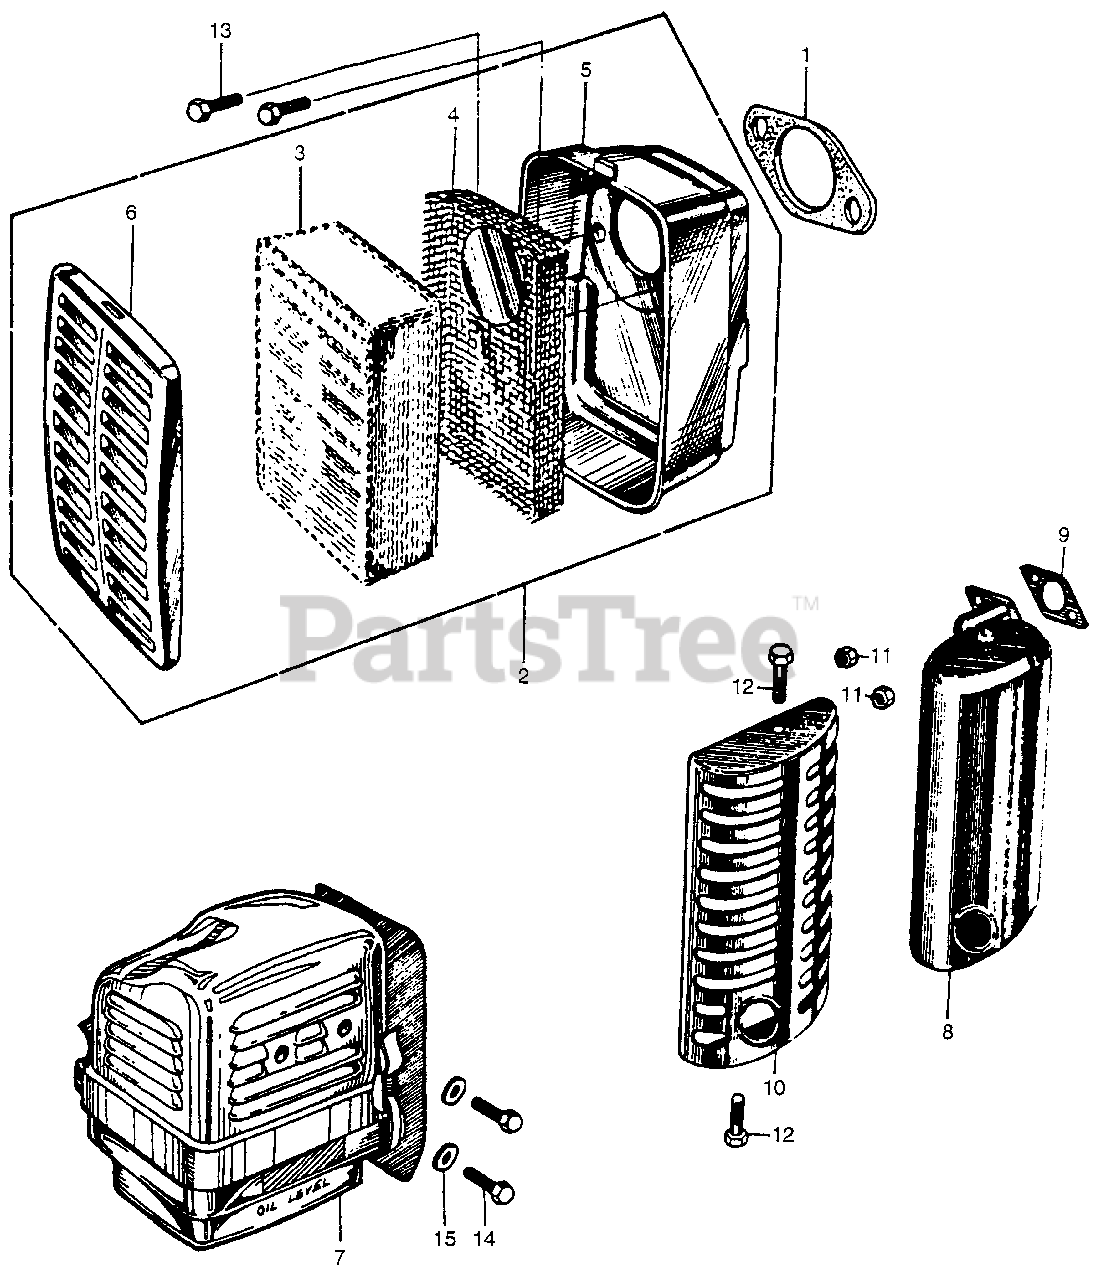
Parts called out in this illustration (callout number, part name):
1	GASKET, AIR CLEANER (NOT AVAILABLE)
2	AIR CLEANER ASSY. (N/A: SEE COMPONENTS)
3	ELEMENT, AIR CLEANER
4	GRID, AIR CLEANER (NOT AVAILABLE)
5	HOUSING, AIR CLEANER *R2* (SCARLET)
6	COVER, AIR CLEANER (NOT AVAILABLE)
7	CLEANER ASSY., OIL BATH TYPE *R2* (SCARLET)
8	MUFFLER (NOT AVAILABLE)
9	GASKET, MUFFLER
10	PROTECTOR, MUFFLER
11	NUT, HEX. (6MM) (NOT AVAILABLE)
12	BOLT, HEX. (6X10) (NOT AVAILABLE)
13	BOLT, HEX. (6X12)
14	BOLT, HEX. (6X90)
15	WASHER, PLAIN (6MM)
